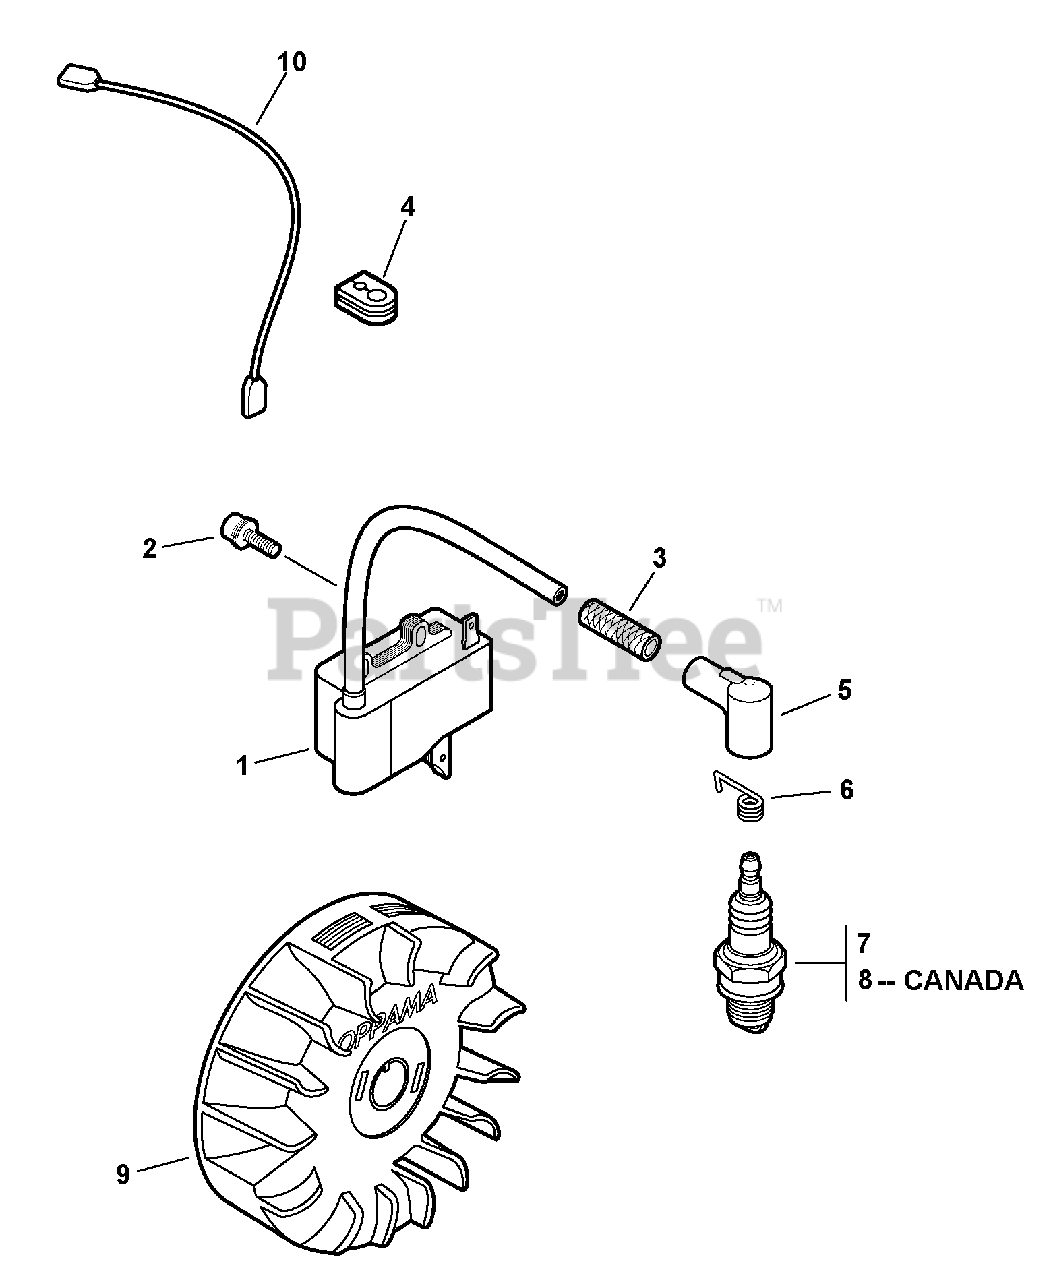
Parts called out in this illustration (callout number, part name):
1	Coil, ignition
2	Screw 4x20
3	Tube, Insulator
5	Cap, Spark Plug
6	Terminal, Spark Plug Cap
7	Spark Plug - BPM-8Y
8	Spark Plug - BPMR-8Y
9	Flywheel
10	Lead, Ignition
